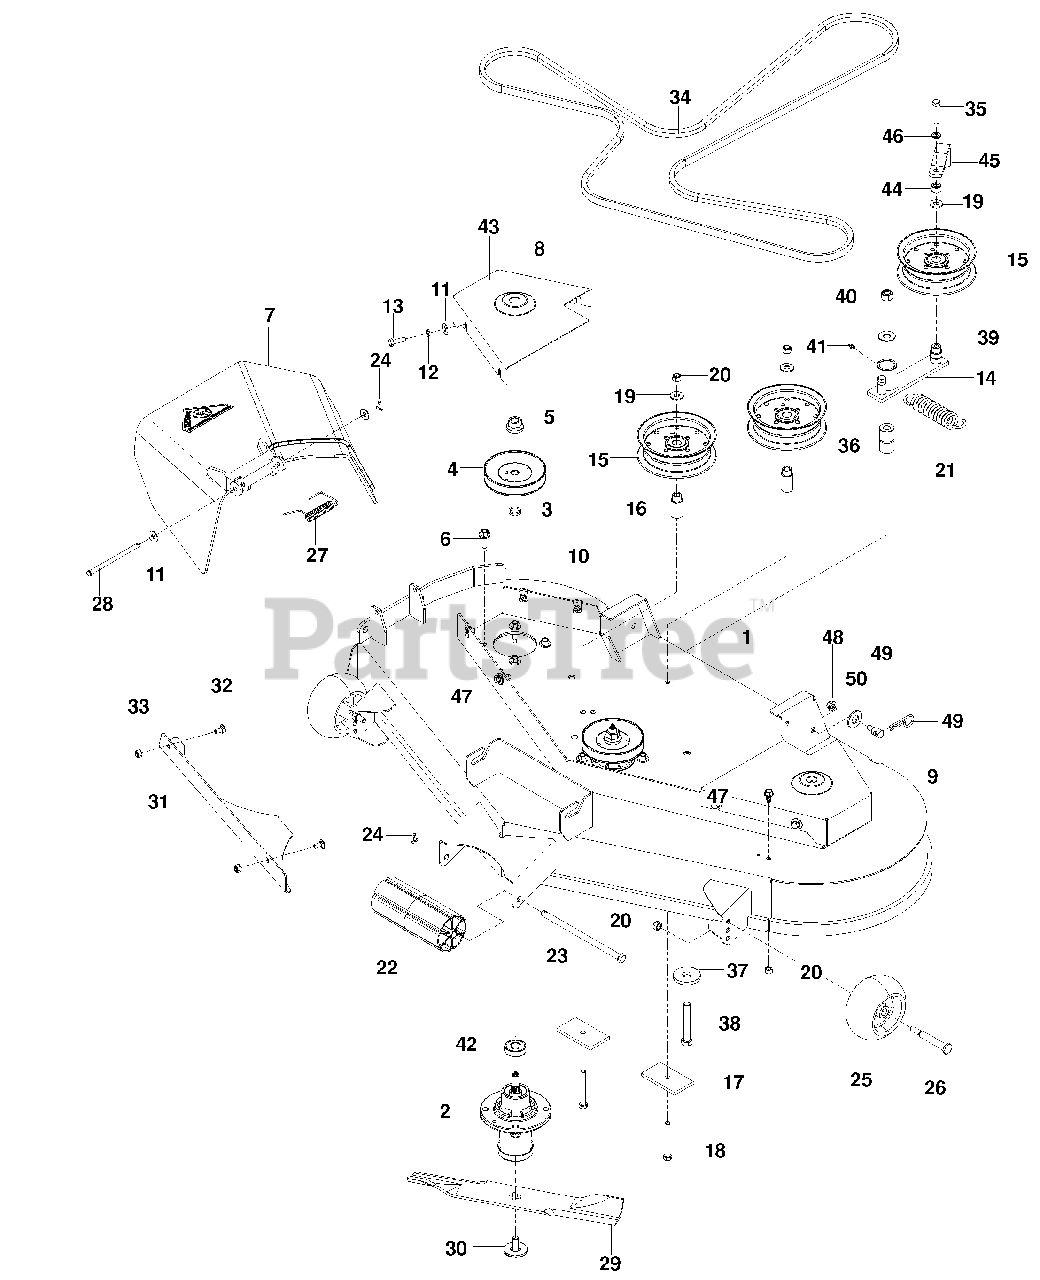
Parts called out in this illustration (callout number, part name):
1	Deck, W/Decals
2	Housing Assy
3	Washer, Spacer
4	Pulley, Mandrel
5	Nut 9/16 Top Cntrlk
6	Screw 5/16 -18 X Wsh Hd
7	Chute, Discharge
8	Belt Shield, Rt
9	Belt Shield, Lt
10	Retainer, U Type
11	Washer 5/16 Std Flat
12	Washer 5/16 Slw
13	Hcs 5/16-18 X 1
14	Arm, Idler
15	Pulley, Idler
16	Bushing, Idler
17	Pad, Painted
18	Hcs 3/8-16 X 3
19	Washer 3/8 Flat Std
20	Nut 3/8-16 Hex Nyloc
22	Roller, Nose
23	Rod, Roller, Nose
24	Pin, Cotter 1/8 X 3/4
25	Wheel, Gauge
26	Bolt 1/2-16 X 25/8 Shoulder
27	Spring, Torsion
28	Pin, Clevis 5/16
30	Bolt 7/16 Blade
31	Plate, Confinement
32	Rhsnb 5/16-18 X 5/8
33	Nut 5/16-18 Hex Nyloc
34	Belt, Deck
35	Hcs 3/8-16 X 1 3/4
36	Bushing, Pivot
37	Washer, Support
38	Hcs 1/2-13 X 3 1/4
39	Washer 1/2 Std Flat
40	Nut 1/2 Hex Nyloc
41	Zerk
42	Bearing, Ball
43	Hairpin #4
45	Guide, Belt
46	Washer 3/8 Splt Lock
47	Screw 3/8-16 X 3/4 Thd Frm
48	Nut 5/16-18 Flange Nyloc
50	Washer 5/8 Sae
